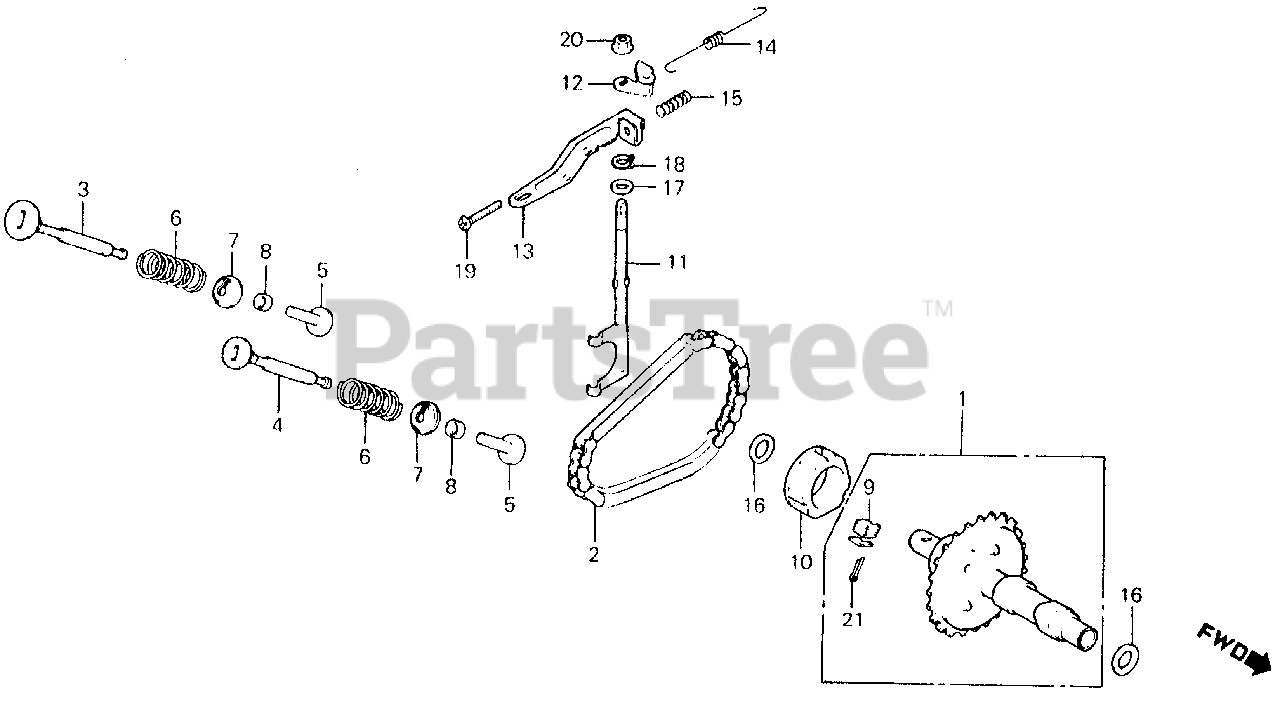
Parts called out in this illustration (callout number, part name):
1	CAMSHAFT ASSY.
2	CHAIN, CAM (NOT AVAILABLE)
3	VALVE, IN.
4	VALVE, EX. (NOT AVAILABLE)
5	LIFTER, VALVE
6	SPRING, VALVE (NOT AVAILABLE)
7	RETAINER, VALVE SPRING
8	ADJUSTER, TAPPET CLEARANCE
9	WEIGHT, GOVERNOR
10	SLIDER, GOVERNOR
11	SHAFT, GOVERNOR
12	PLATE, GOVERNOR ADJUSTING
13	ARM, GOVERNOR (NOT AVAILABLE)
14	SPRING, GOVERNOR (NOT AVAILABLE)
15	SPRING, CONTROL ADJUSTING
16	WASHER, THRUST (9.9MM)
17	WASHER, PLAIN (6MM)
18	CIRCLIP (5MM)
19	SCREW, PAN (4X20)
20	NUT, FLANGE (5MM)
21	PIN, COTTER (2.0X15)
